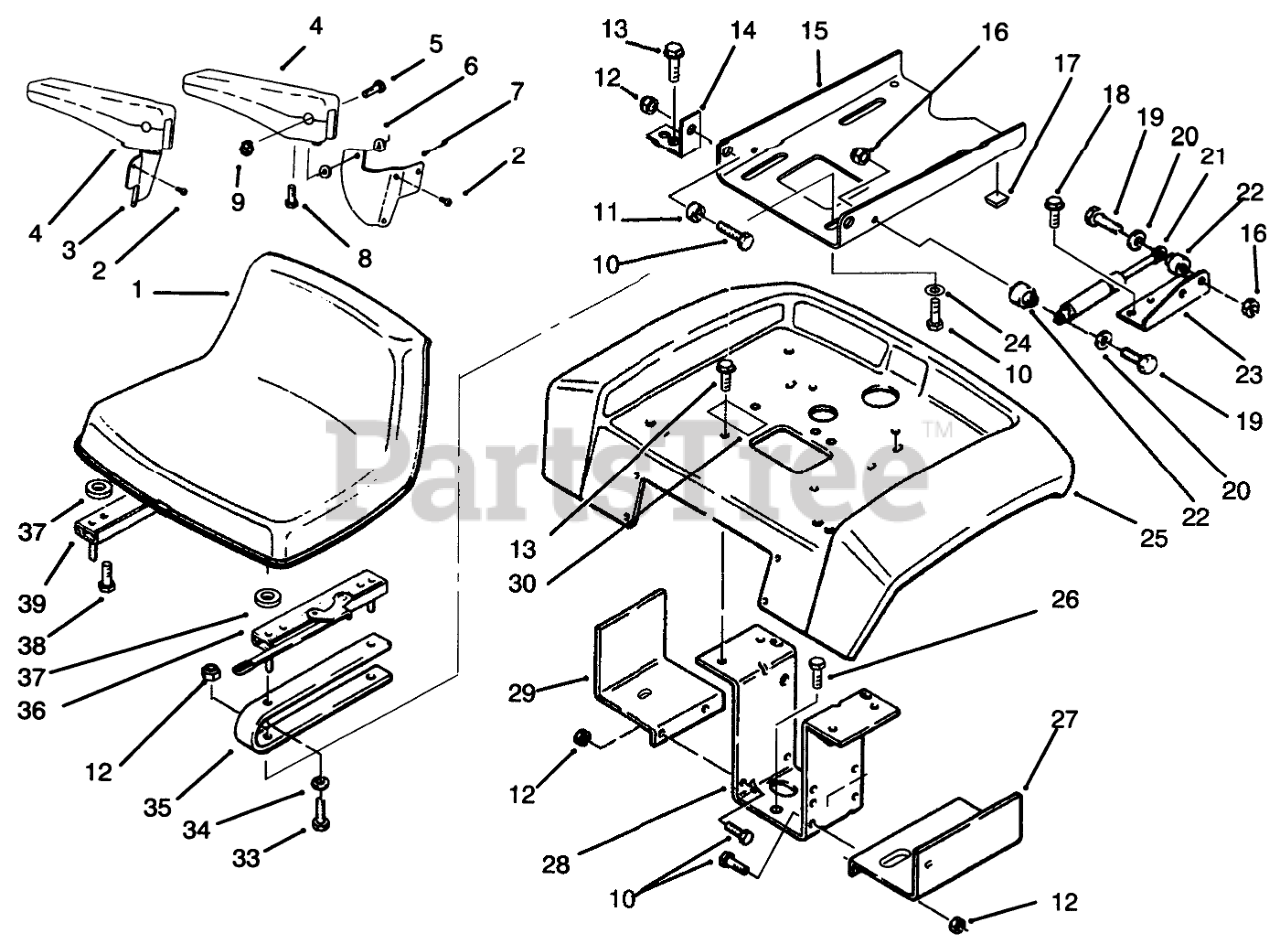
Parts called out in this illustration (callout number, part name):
1	Seat
2	3/8-16 X 5/8 SCREW
3	RH ARM BRACKET
4	ARMREST
5	3/8-16X1-1/2 SCREW
6	NYLON SPACER
7	LH ARM BRACKET
8	3/8-16 X 3/4 SCREW
9	3/8-16 ACORN LOCKNUT
10	SCREW-HH
11	BUSHING
12	NUT-LOCK, NI
13	Bolt
14	BRACKET-PIVOT
15	Plate-SeatPivot
16	NUT-LOCK, NI
17	BUMPER SJ5514 BLACK
18	Bolt
19	SCREW-HH
20	WASHER-FLAT
21	GAS SPRING
22	SPACER
23	BRACKET-CYLINDER R
24	WASHER-PLAIN
25	Fender
26	SCREW-HH
27	Fuel Tank Support LH
28	Bracket-Fender
29	Support-FueITank RH
30	DECAL-DO NOT TOW
33	SCREW-HH
34	WASHER-LOCK
35	Seat Spring
36	Adjuster-Seat
37	SPACER-NYLON
39	ADJUSTER-R.H. SEAT
